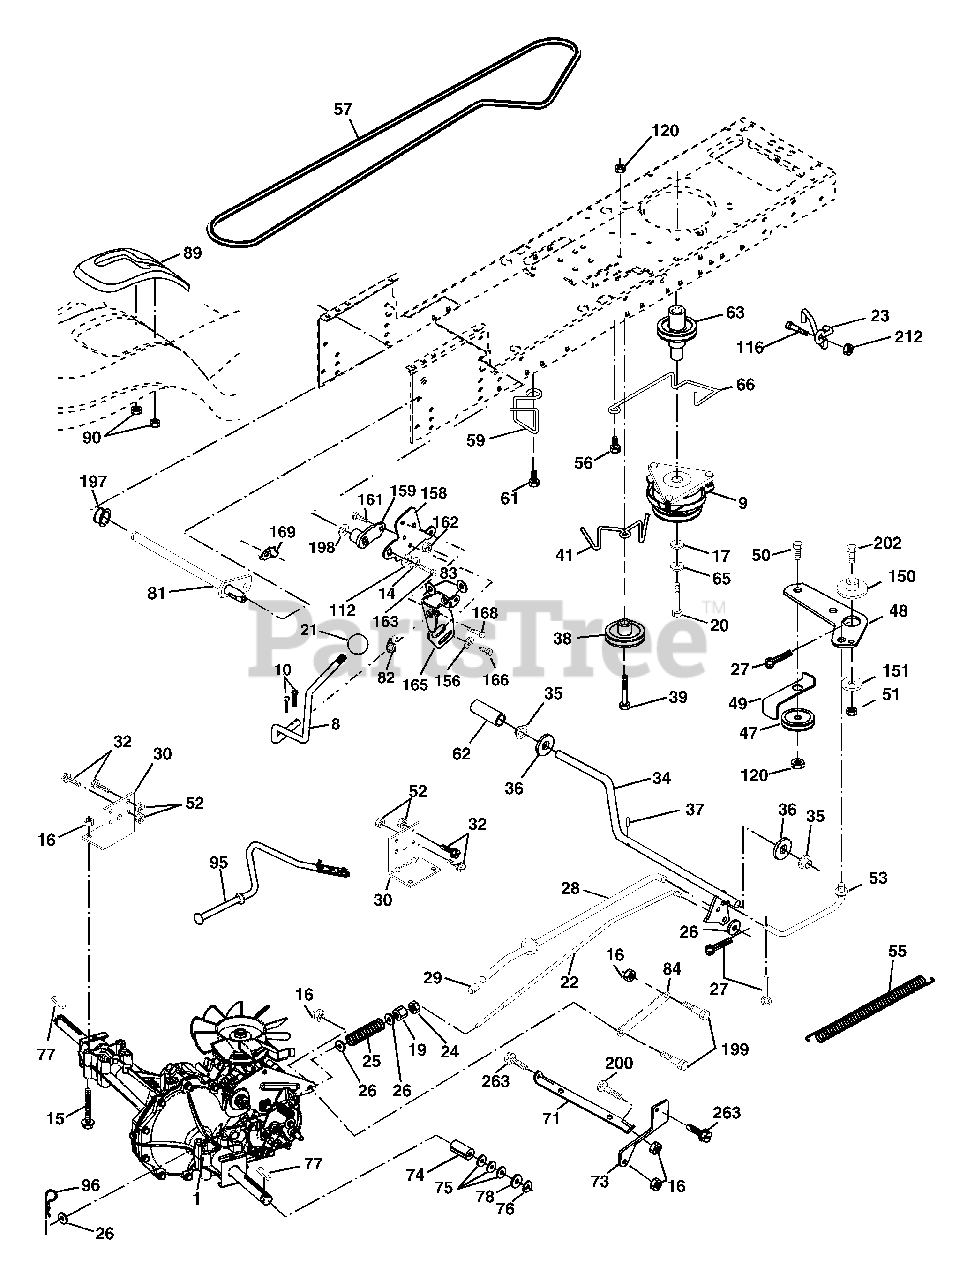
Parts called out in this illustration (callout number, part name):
8	Rod Shift Fender
9	Clutch Electric
10	Pin Cotter 1/8 x 1 CAD
14	Washer Lock Hvy Helical
15	Bolt Hex Flghd 5/16-18 Gr. 5
16	Nut Lock Hex W/Ins. 5/16-18 unc
17	Washer 1-1/2 OD x 15/32 ID x .250
19	Nut Lock Hex W/Wsh 3/8-16 unc
20	Bolt, Hex 7/16-20 x Gr. 5-1.5
22	Rod, Brake Hydro
23	Bracket Asm. Anti-Rot CVX
24	Locknut
25	Spring, Brake Rod
26	Washer
27	Pin Cotter 1/8 x 3/4 CAD.
28	Rod, Parking Brake
29	Cap, Parking Brake
30	Bracket, Transaxle
32	Bolt Hex Hd 5/16-18 unc x 3/4
34	Shaft, Foot Pedal Nibbed
35	Bearing, Nylon
37	Pin, Roll
38	Pulley, Idler, Flat Composite
39	Bolt 3/8-16 x 2-3/4 Gr. 5
41	Keeper, Belt Idler Fool-Proof
47	Pulley, Idler, V-Groove
48	Bellcrank Clutch Grnd Drv Stl
49	Retainer, Belt
50	Bolt Carr. SH 3/8-16 x 1-1/2 Gr. 5
52	Nut Crown Lock 5/16-18
53	Link, Clutch
55	Spring, Return, Clutch
56	Screw 3/8-16 x 1-1/4
57	V-Belt, Ground Drive
59	Keeper, Center Span
61	Screw 3/8-16 x .875
62	Cover, Pedal
63	Pulley, Engine
65	Washer
66	Keeper Belt Engine Hydro
71	Strap Torque Lh Hydro
73	Strap Torque Rh Hydro
74	Spacer, Axle
75	Washer 25/32 x 1-1/4 x 16 Ga.
77	Key, Square
78	Washer 25/32 x 1-5/8 x 16 Ga.
81	Shaft Asm. Cross Hydro
82	Spring Torsion T/A
83	Washer 17/32 x 3/4 x 16 Ga.
84	Link Transaxle
89	Console, Shift
90	Nut, Self Thd Wsh Hd 1/4 Zinc
95	Control Asm. Bypass Hydro
96	Retainer Spring 1" Zinc/Cad
112	Washer 9/32 x 3/4 x 10 Ga.
116	Bolt RDHD SQNK 3/8-16 unc x 1
120	Nut Lock 3/8-16
150	Spacer Retainer
151	Washer 13/32 x 2 x 10 Ga.
156	Washer Srrted 5/16 ID x 1.125
158	Bracket Shift Mount
159	Hub Shift
161	Bolt Rdhd Sqnk 1/4-20 x 3/4 Gr. 5
162	Nut Crownlock 1/4-20 unc
163	Bolt Hex Fin 1/4-20 unc x 1 Gr. 5
165	Bracket Pivot Lever
166	Screw 5/16-18 x 5/8
168	Bolt Shoulder 5/16-18 x .561
169	Plate Fastening Lt\
197	Nyliner Snap-In 5/8" ID
198	Washer Nyliner 7/8 ID x .105
199	Bolt Shoulder 5/16-18 unc
200	Bolt Rdhd Sq Neck 5/16-18 unc x 1
202	Bolt 3/8-16 x 1-3/4 Gr. 5
212	Nut Hexflange Lock
263	Screw Hexwsh Thdr 3/8-16 x 3/4
